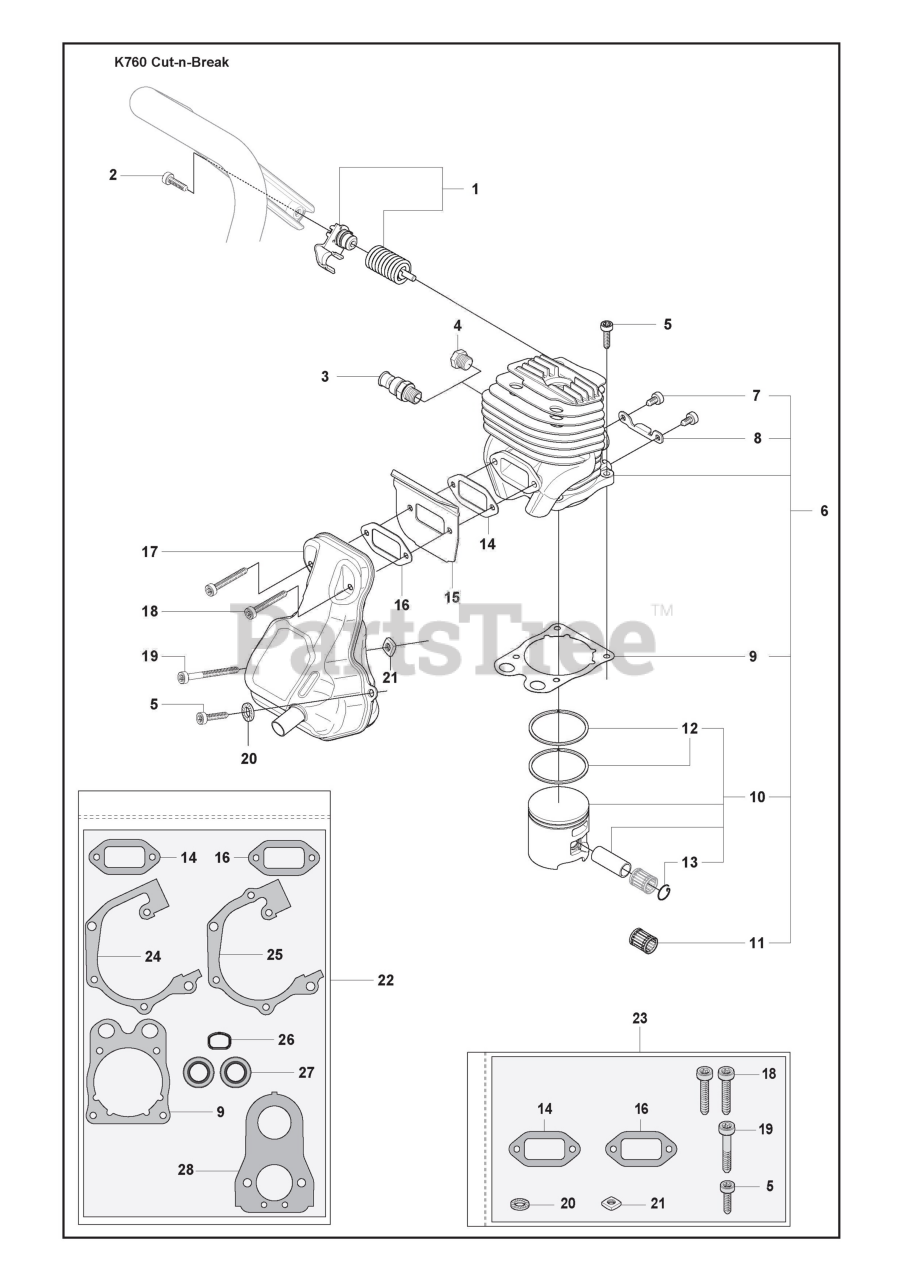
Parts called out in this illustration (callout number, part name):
1	Vib.Insulator
3	Decompression Valve
6	Cylinder Assy
9	Cylinder Base Gasket
10	Piston Assy
11	Needle Bearing
12	Piston Ring
15	Cooling Plate
16	Gasket Muffler
17	Muffler
22	Gasket Kit
23	Muffler Mounting Kit
24	Gasket Crankcase
25	Gasket Crankcase
27	Sealing Ring
28	Gasket Carburettor
